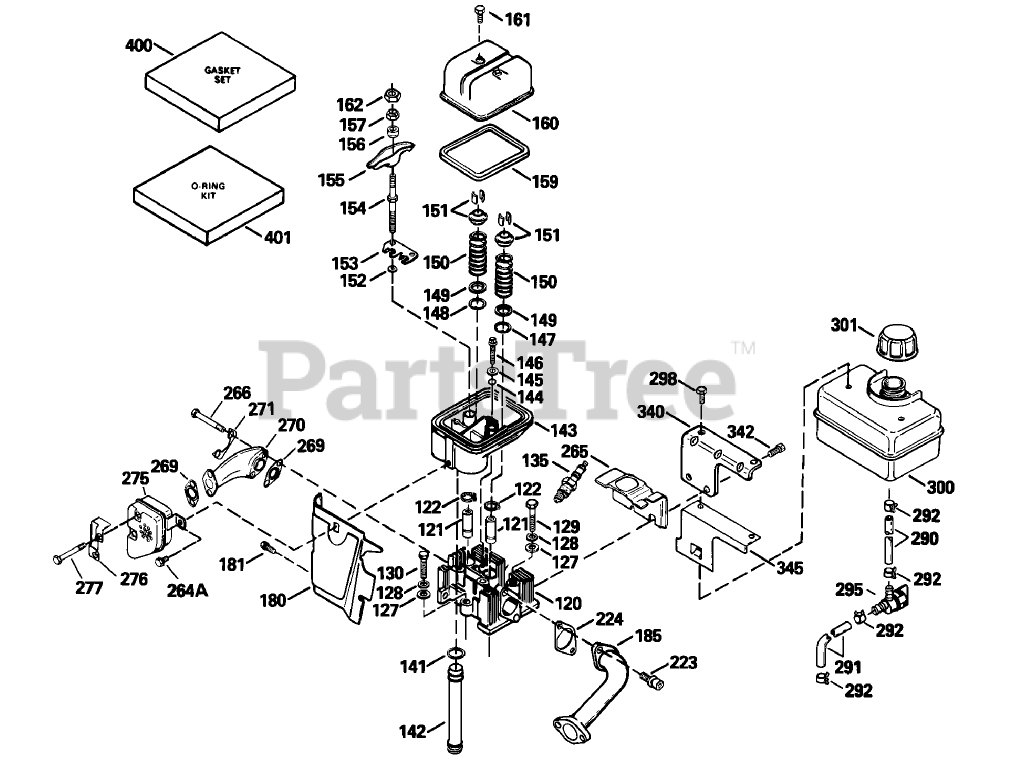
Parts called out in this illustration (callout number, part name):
120	Cylinder Head
121	Valve Guide Kit (Incl. Ref.# 2 of 122)
122	Ring-Snap
127	Washer-Flat
128	Washer-Belleville
129	Screw
130	Screw
135	Spark-Plug (RL86C)
141	ORing
142	Push Rod Tube
143	55062 SNWTHWR ADN.W
144	ORing
145	Washer
146	Bolt-Rod, Connecting
147	ORing
148	O-Ring (Also Incl. in 401)
149	Cap-Valve Spring
150	Spring-Valve
151	Keeper-Spring, Valve
152	O-Ring (Also Incl. in 401)
153	Guide-Push Rod
154	Rocker Arm Stud
155	Arm-Rocker
156	Bearing-Rocker Arm
159	ORing
160	Housing-Rocker Arm
161	Screw
162	Jam Nut
180	Blower Housing Extension
181	Screw
185	Intake Pipe
223	Screw (T-30, 5/16-18 X 7/8)
224	Gasket-Pipe
264A	Screw
265	Cover-Cylinder Head
266	Screw (5/16-18 X 1-9/32)
269	Gasket-Manifold, Exhaust
270	Exhaust Manifold
271	Plate-Locking
275	Muffler
276	Plate-Locking
277	Screw (5/16-18 X 4-1/2)
290	Line-Fuel
291	Line-Fuel (8.62)
292	Clamp-Line, Fuel
295	Valve-Shut Off, Fuel
